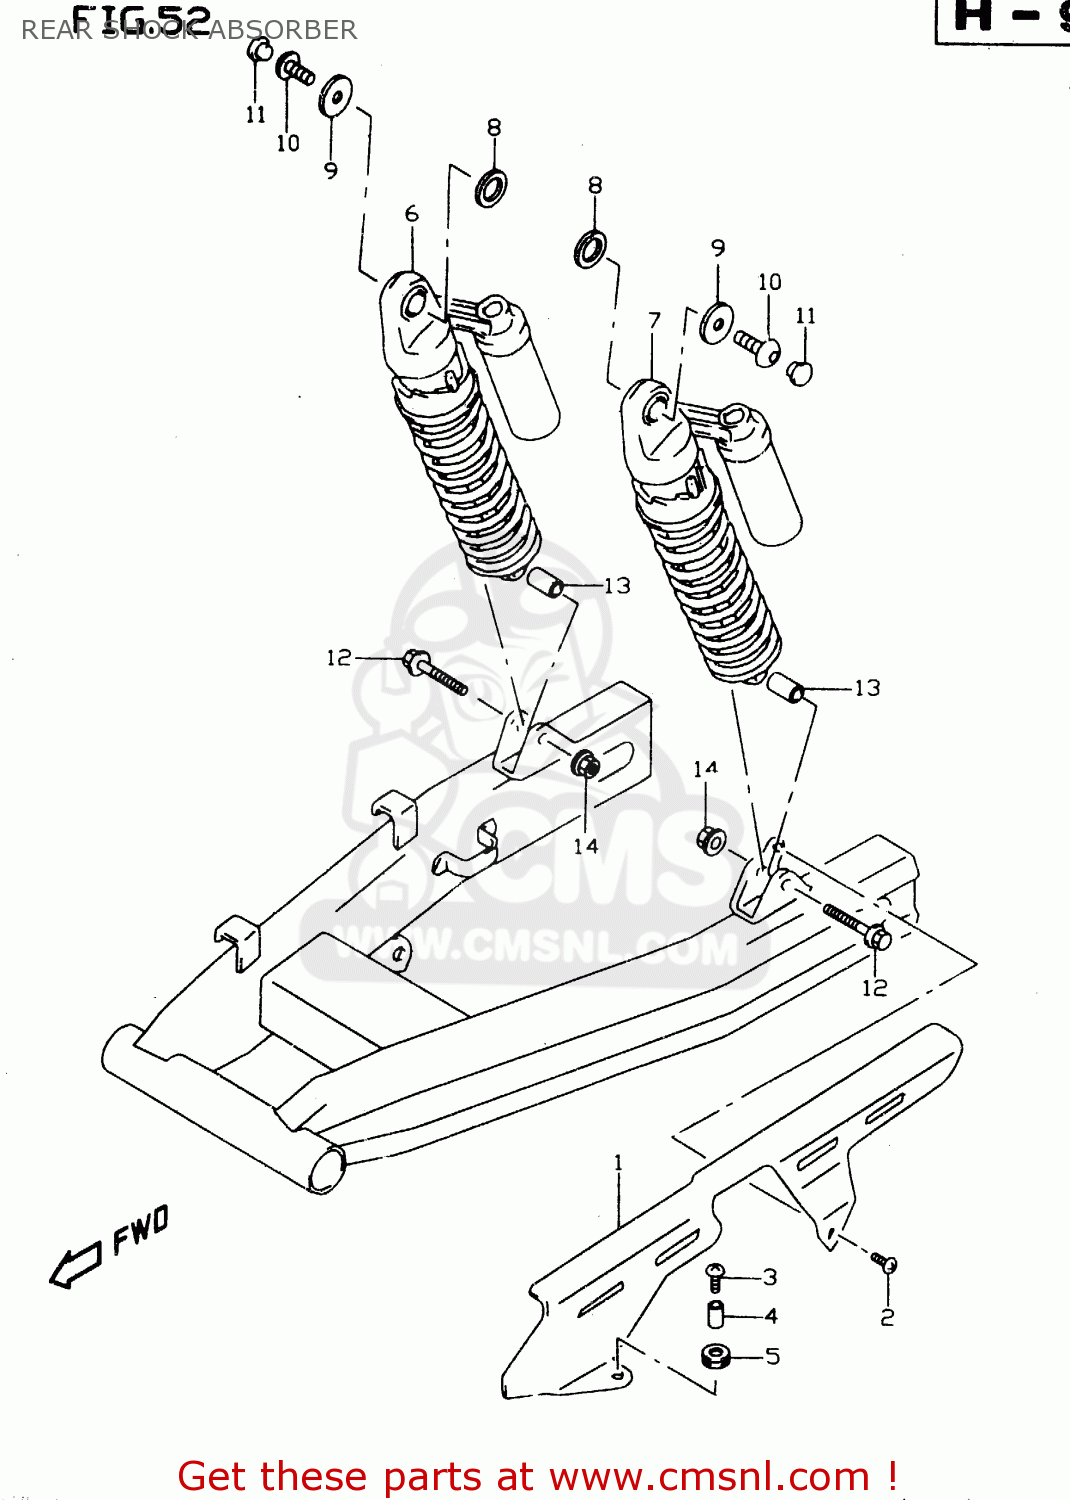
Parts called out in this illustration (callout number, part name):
1	CASE,CHAIN
2	SCREW
3	SCREW (6X16)
4	SPACER(6.2X8.3X6.1)
5	CUSHION
6	ABSORBER ASSY,
7	ABSORBER ASSY,
8	WASHER(14.5X30X3.2)
9	WASHER (8.5X30X2.3)
10	BOLT(8X20)
11	CAP(OD:10)
12	BOLT(10X45)
13	SPACER(10.2X14X20.7)
14	NUT
